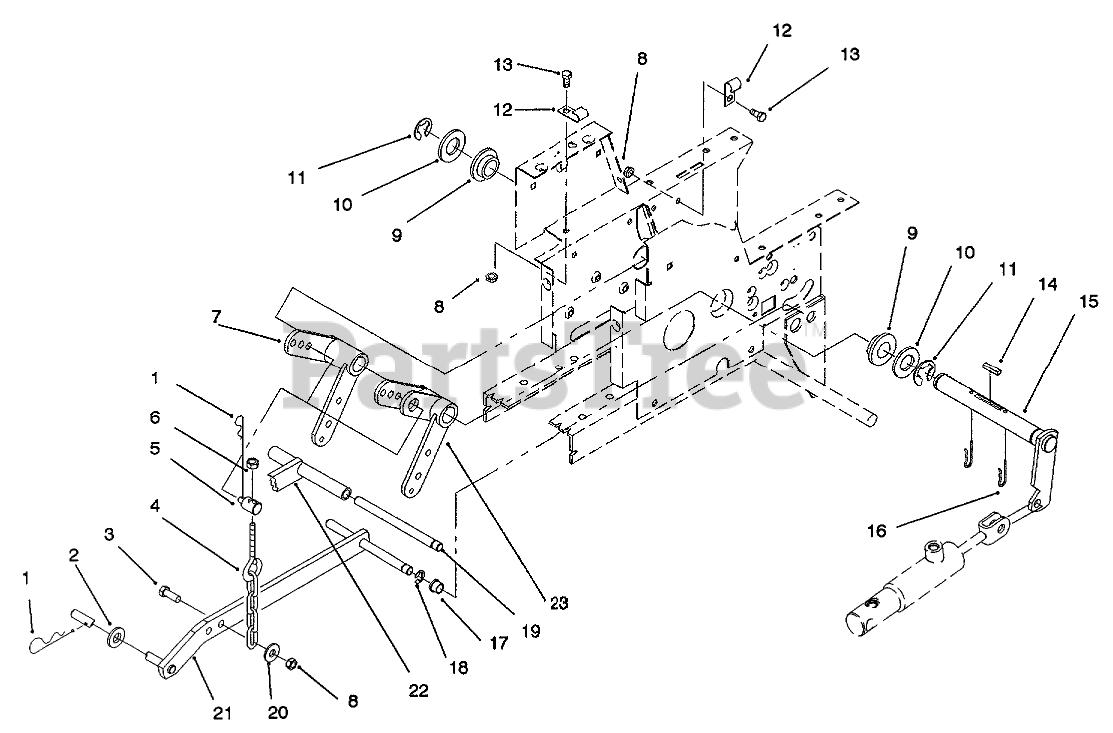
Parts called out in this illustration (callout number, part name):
1	PIN-HAIR
2	WASHER-FLAT
3	SCREW-HH
4	CHAIN-LIFT
5	TRUNNION-LIFT
6	NUT-LOCK, NI
7	LIFT LEVER ASM
8	NUT-LOCK, NI
9	BEARING-FLANGE
10	WASHER-FLAT
11	RING-RETAINING
12	CLIP
13	SCREW-HH
14	KEY-SQUARE
15	WLDMT-LIFT ARM
16	PIN-HAIR
17	BUSHING
18	RING-RETAINING, EXTERNAL
20	WASHER-PLAIN
21	Bar-Lift
